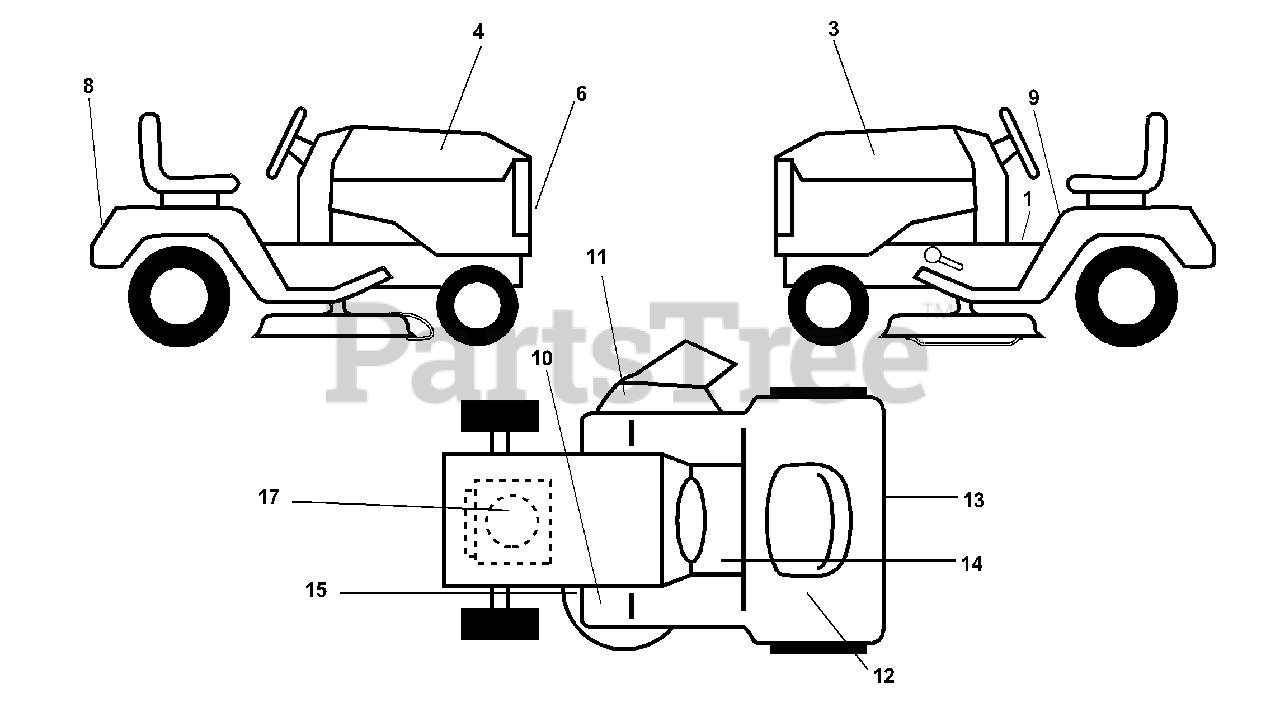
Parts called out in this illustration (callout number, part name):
1	Decal Instruction Dash Eng/fr
3	Decal Hood LH
4	Decal Hood RH
6	Decal Grille
8	Decal Fender Logo
9	Decal Caution Fender Eng/fr
10	Decal Clutch/brake Eng/fr
11	Decal Warning Multi-Language
12	Decal Bat Dan/Poi P/L Sym WPN
13	Decal Drawbar CNTRL MVT HYD LT
14	Decal SDL COLD START HYD E/F
15	Decal V-Belt Schematic
17	Decal Engine Kohler 13 HP
